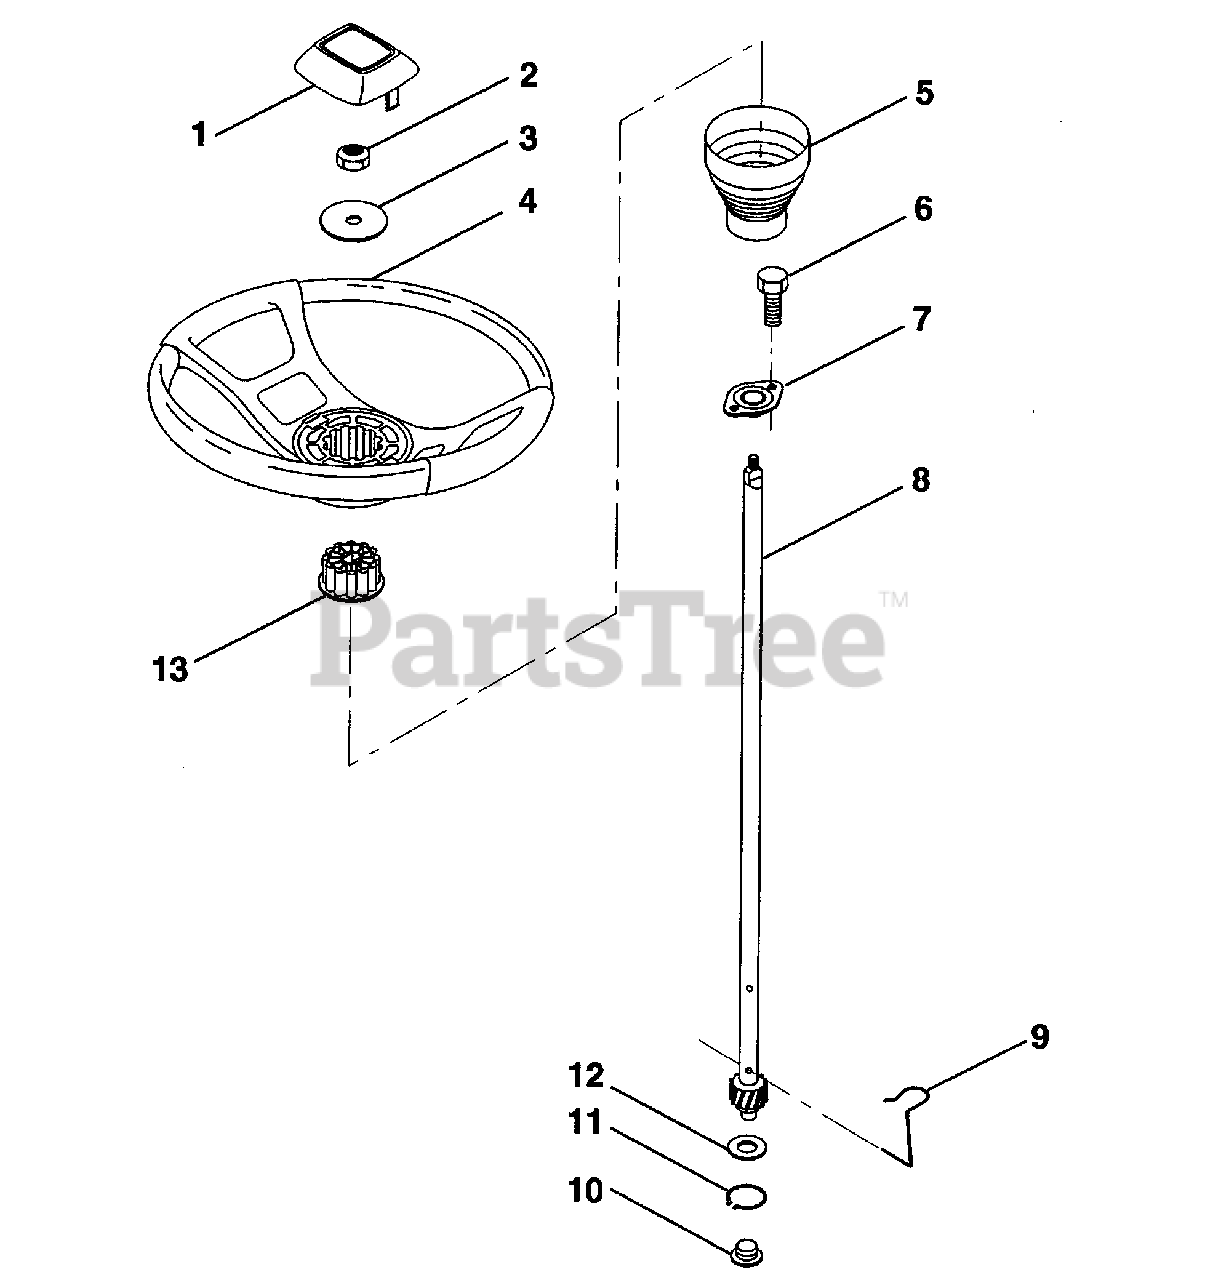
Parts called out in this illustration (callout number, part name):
1	Insert, Steering Wheel (AYP part number)
2	Locknut 3/8-24 UNF (AYP part number)
3	Washer 13/32 x 2-3/8 x 8 Gauge (AYP part number)
4	Steering Wheel (AYP part number)
5	Sleeve, Steering (AYP part number)
6	Screw, Hex, Self-Tapping #10-16 x 1/2 (AYP part number)
7	Bushing, Steering (AYP part number)
8	Shaft, Steering (AYP part number)
9	Clip, Steering (AYP part number)
10	Bushing, Lower, Steering (AYP part number)
11	Ring, Retaining (AYP part number)
12	Washer 21/32 x 1 x 16 Gauge (AYP part number)
13	Adaptor, Steering Wheel (AYP part number)
